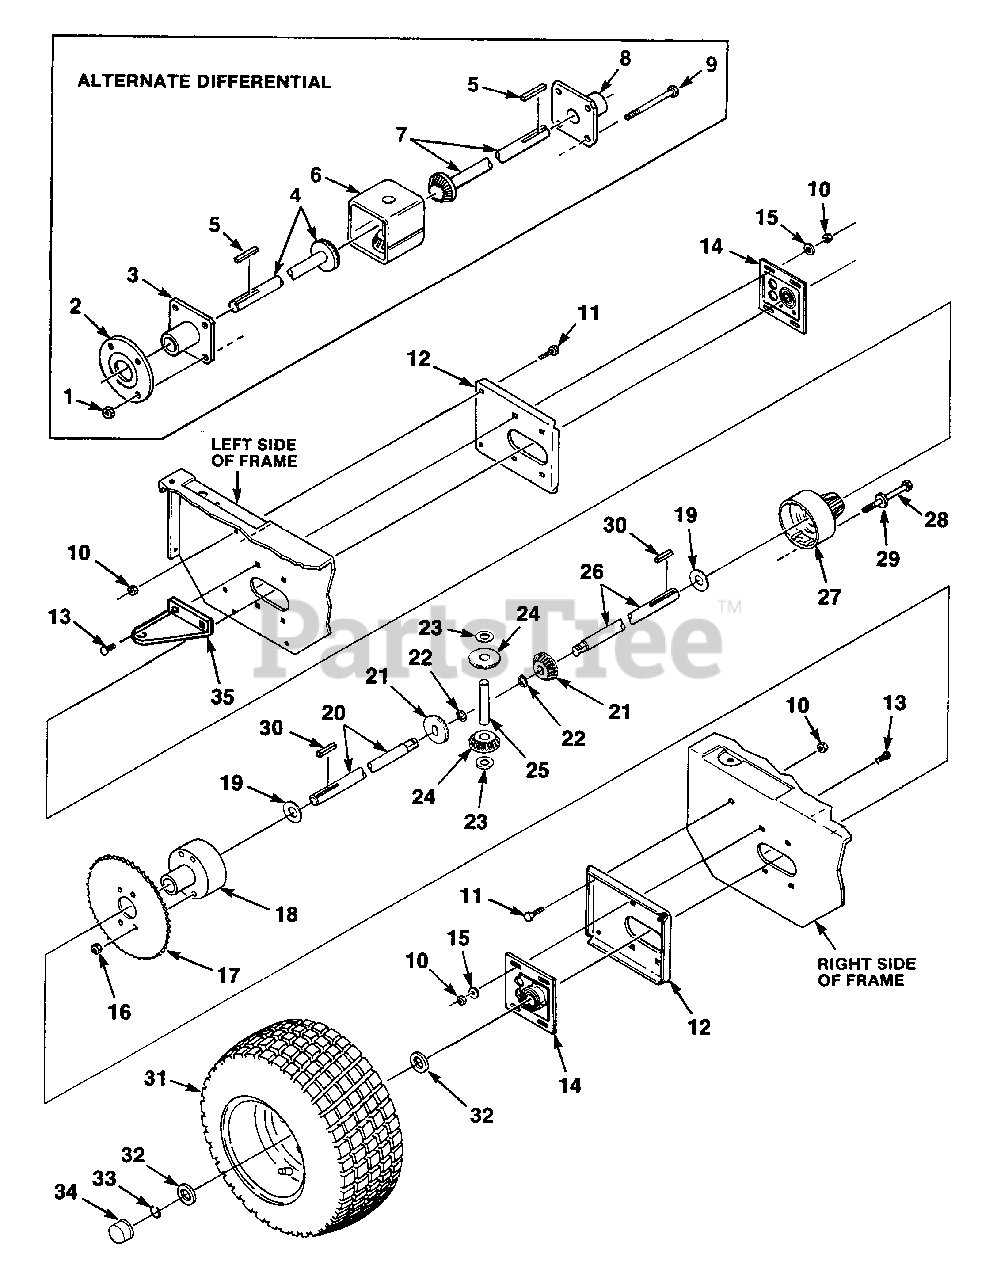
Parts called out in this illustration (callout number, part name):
1	NUT- Hex 5/16-18
2	SPACER- Differential
3	CAP & BEARING
4	AXLE- R.H. W/Gear
5	KEY (not part of differential)
6	HOUSING & GEAR
7	AXLE- L.H. W/Gear
8	CAP & BEARING
9	SCREW- Hex 5/16-18 x 4
10	NUT- 1/4-20 lock
11	SCREW- 1/4-20 x 5/8
12	SUPPORT- Frame
13	BOLT- 1/4 x 3/4
14	RETAINER & BEARING
15	WASHER
16	NUT- Centerlock 3/8-16
17	SPROCKET- 48 tooth
18	HOUSING- Gear
20	AXLE- Short
21	GEAR- Bevel
22	RING- Snap
23	WASHER- Thrust
24	GEAR- Pinion
25	PIN- Drive
26	AXLE-Long
27	GEARING HOUSING
28	SCREW- Mach hex hd.
31	TIRE & HUB (rear)
32	SPACER- Axle
